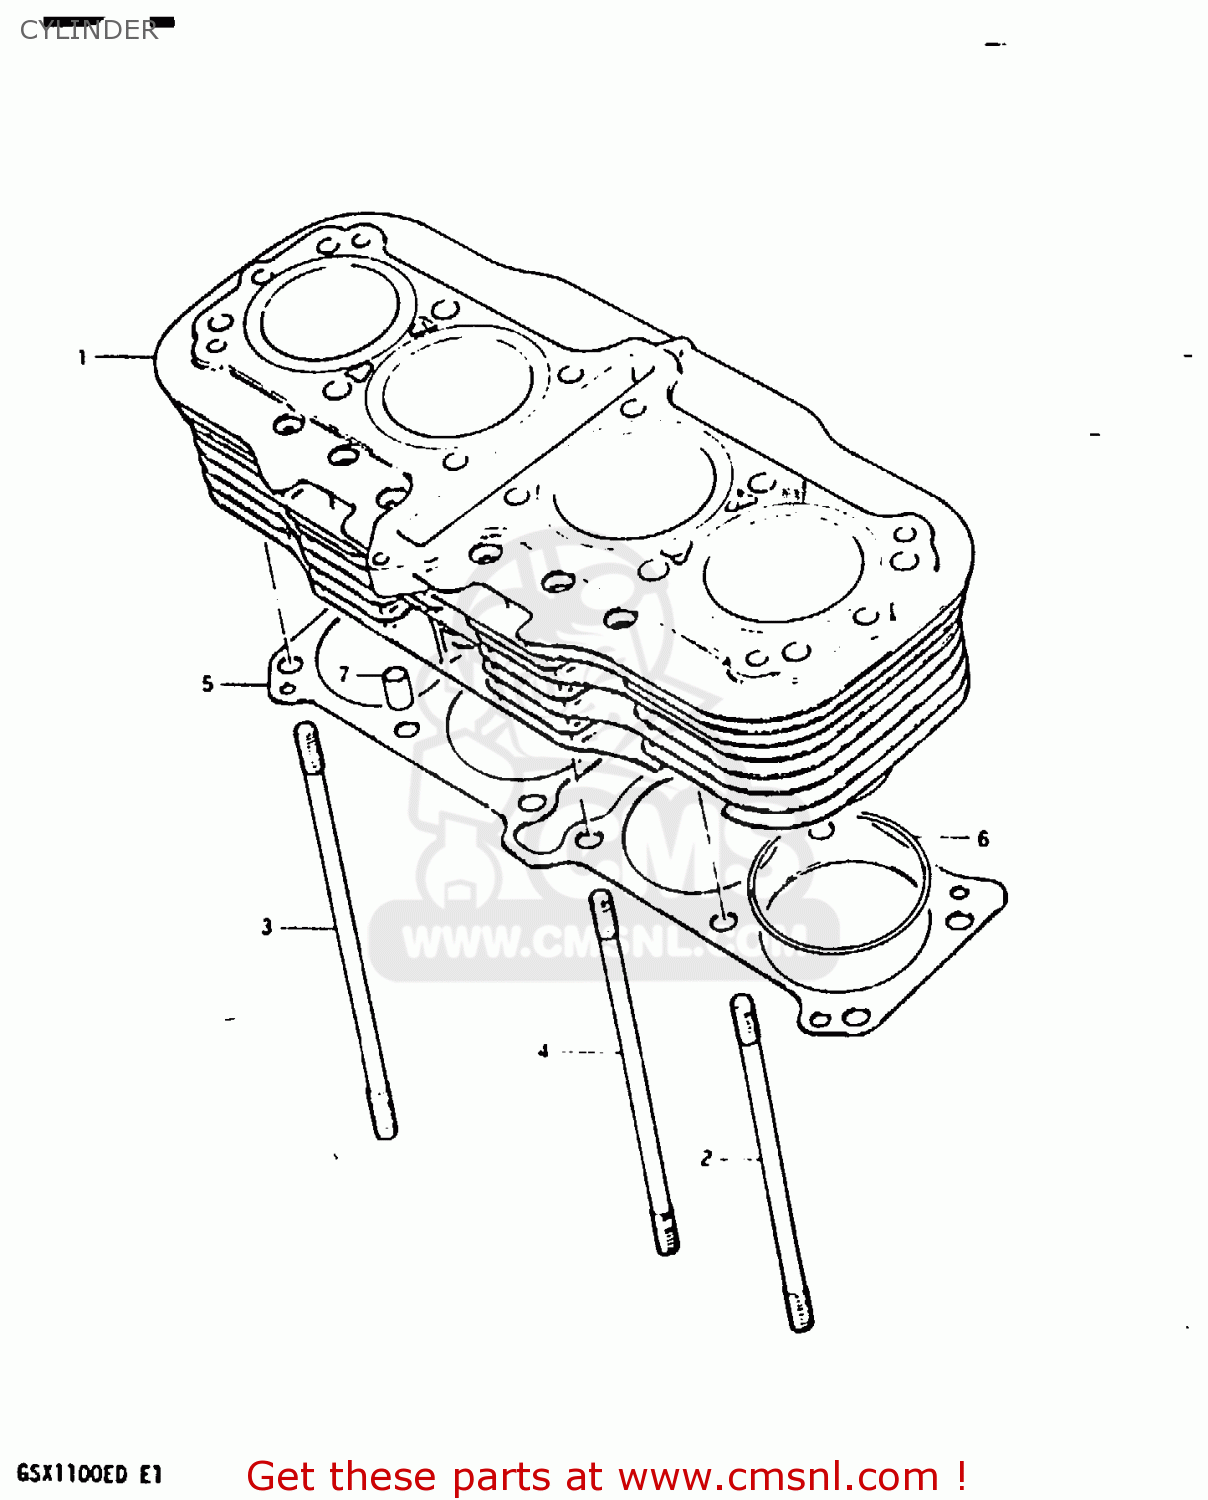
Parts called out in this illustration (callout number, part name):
1	CYLINDER
2	BOLT,STUD
3	STUD
4	BOLT,STUD
5	GASKET,CYLINDER (MCA)
6	O RING(D:2,ID:74)
7	PIN
